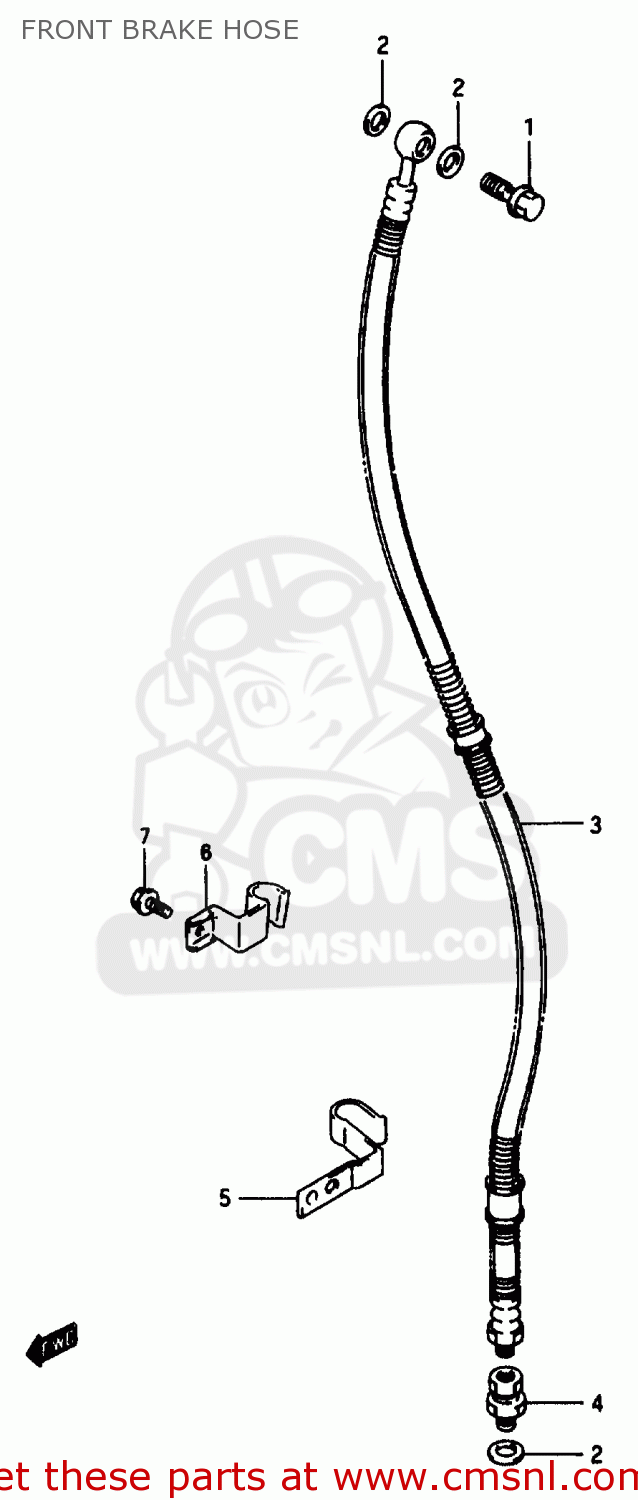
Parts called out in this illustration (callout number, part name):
1	BOLT UNION
2	WASHER(10X15X1.5)
3	HOSE,FR BRAKE
4	ADAPTER,BRAKE HOSE
5	GUIDE,BRAKE HOSE
6	GUIDE,BRAKE HOSE
7	BOLT
